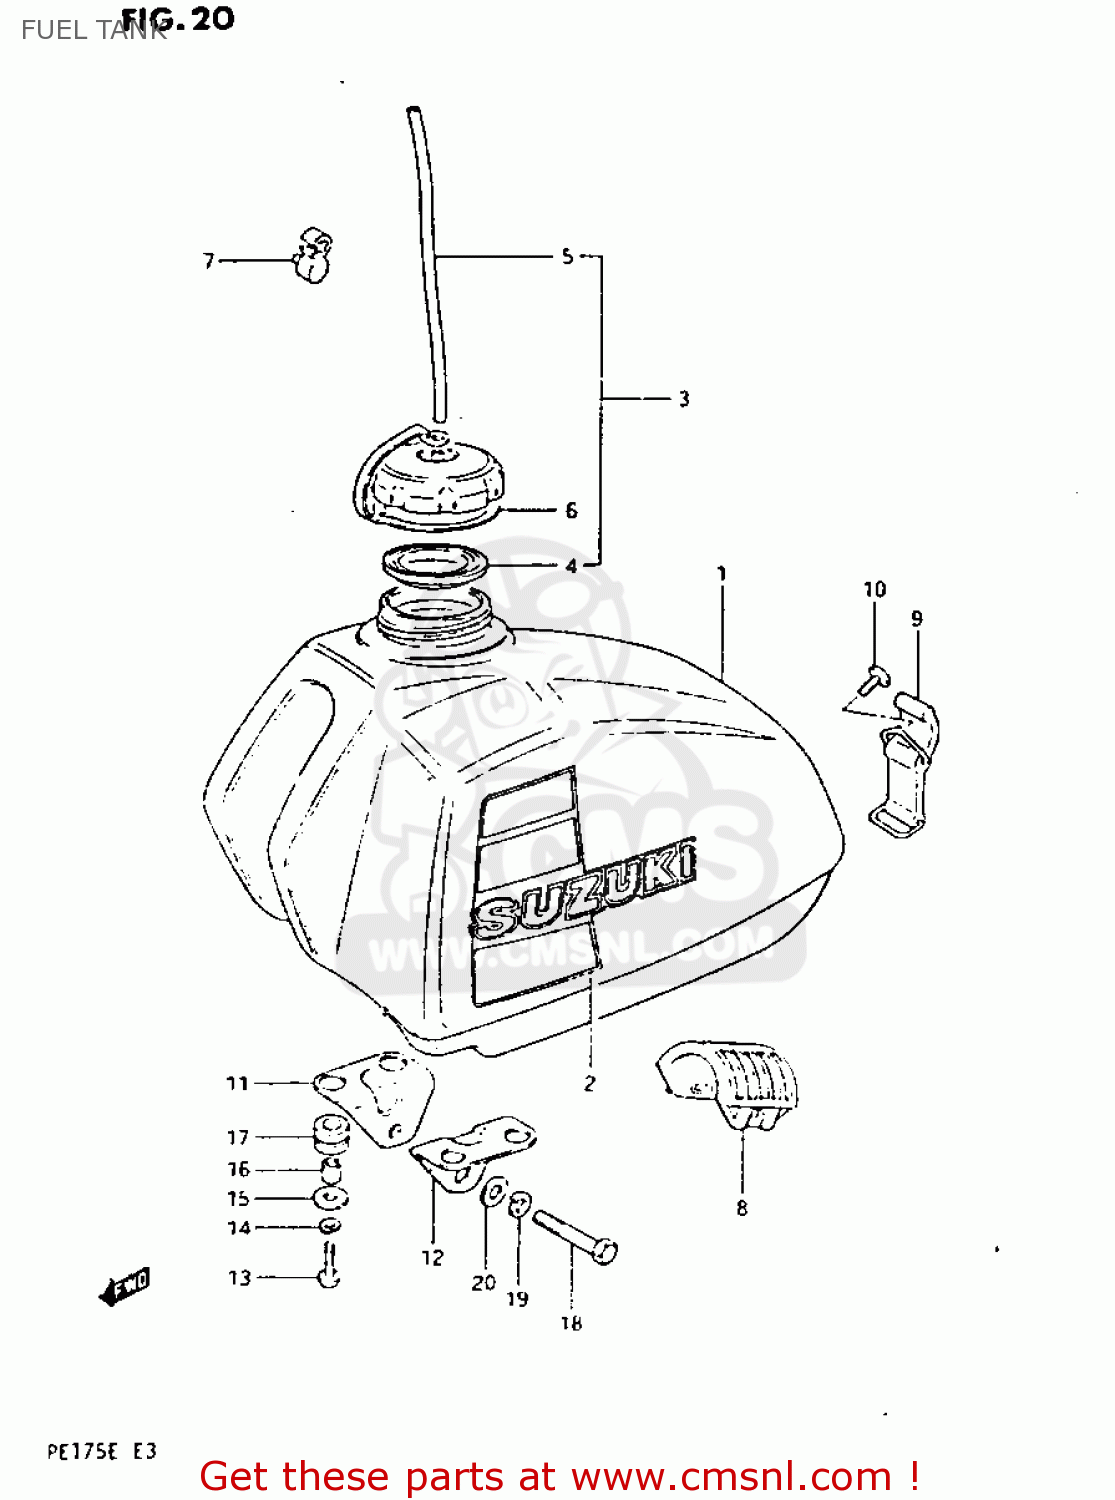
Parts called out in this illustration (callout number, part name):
1	TANK ASSEMBLY,FUEL
2	TAPE SET,FUEL TANK
3	CAP,FUEL TANK
4	GASKET,FUEL TANK CAP (NAS)
5	HOSE
6	BAND,FUEL TANK CAP
7	CLAMP,BREATHER HOSE
8	CUSHION,FUEL TANK
9	BAND,FUEL TANK,REAR
10	SCREW(6X18)
11	BRACKET,FUEL TANK,LOWER
12	BRACKET,FUEL TANK
13	SCREW
14	WASHER,LOCK
15	WASHER (6.5X24X1.6)
16	SPACER(6.8X12X11)
17	CUSHION
18	HEXAGON BOLT 8X80
19	LOCK WASHER
20	WASHER
